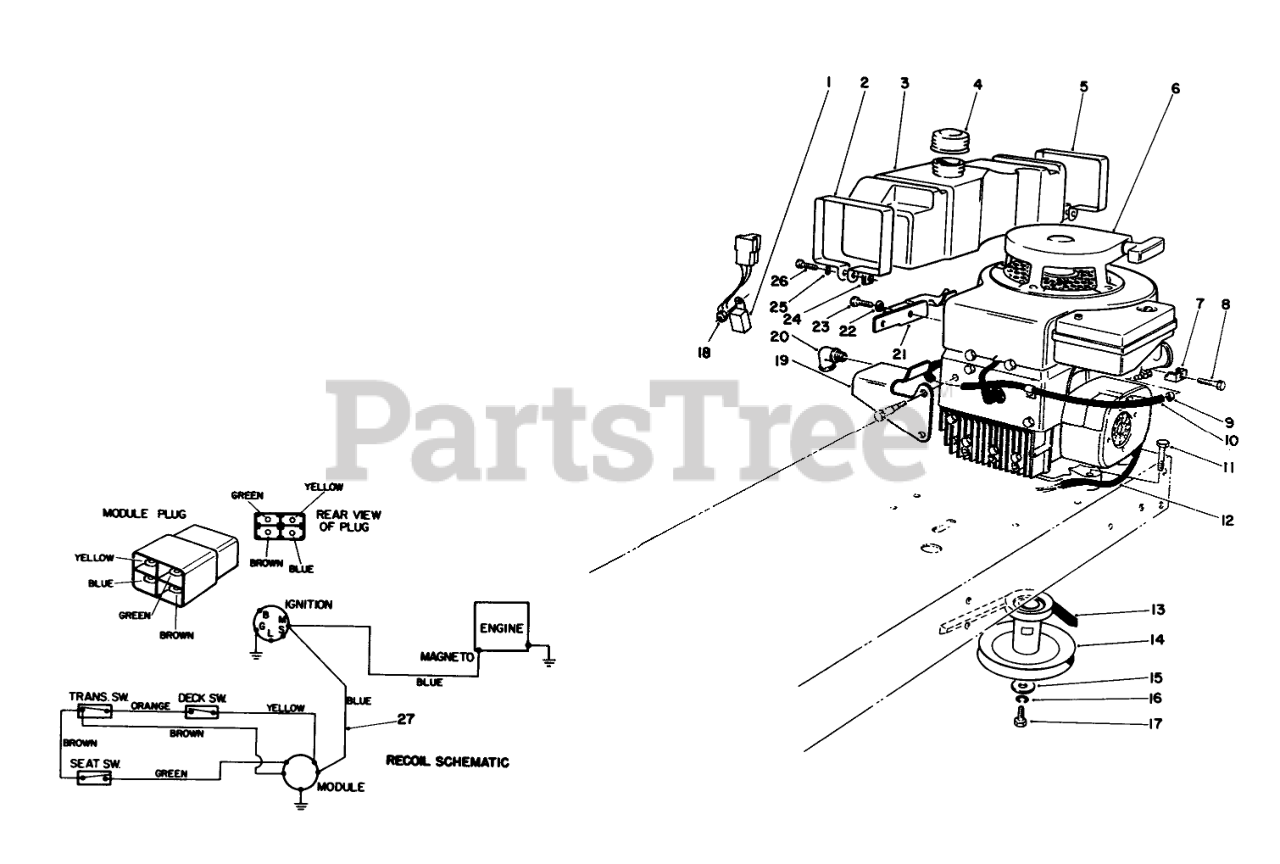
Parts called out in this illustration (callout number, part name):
1	INTERLOCK MODULE
2	Retainer-Front
3	TANK-5 QT GAS
4	GAS CAP ASM
5	Retainer-Rear
6	Engine
7	CLAMP-CASING
8	SCREW W ENGINE
9	FUEL HOSE CLAMP
10	HOSE-FUEL
11	SCREW-HH
12	HEAT SHRINK TUBING
13	V-BELT, TRACTION
14	PULLEY
15	WASHER-FLAT
16	WASHER-LOCK
17	SCREW-HH
18	NUT-LOCK, CONE
19	FRT TANK MTG BRKT B
20	ELBOW-STREET, 90 DEG
21	REAR TANK MTG BRKT B
22	WASHER-PLAIN
23	SCREW-HH
24	NUT-SQUARE
25	WASHER-LOCK
26	SCREW-HSH
27	Wire Harness
